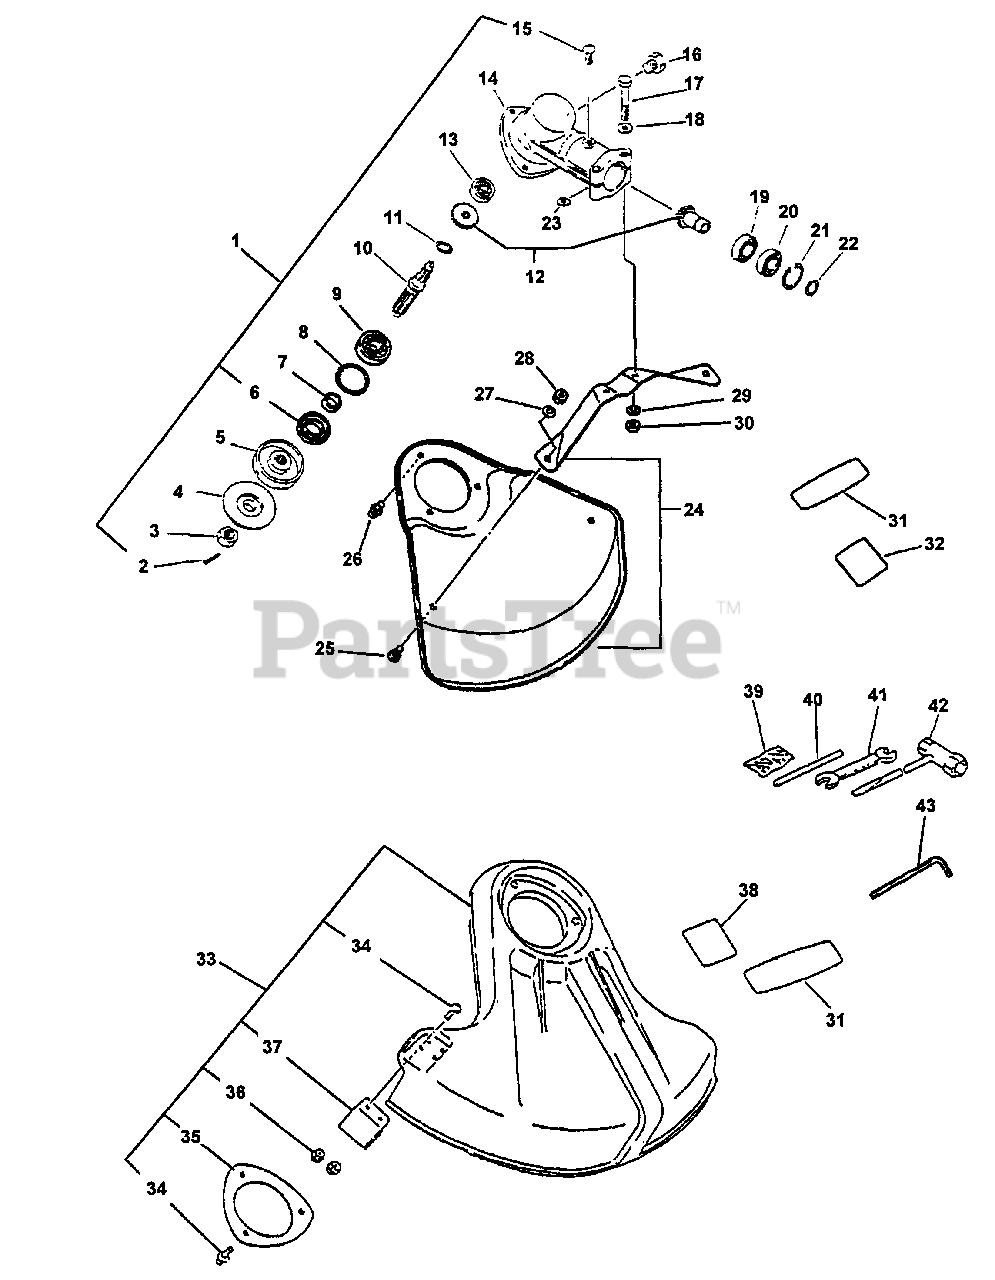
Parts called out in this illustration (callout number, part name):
1	CASE, GEAR - UPPER
2	PIN, SPLIT - 2X22
3	NUT - 10 -- LEFT HAND
4	ADAPTOR, BLADE - LOWER
5	ADAPTOR, BLADE - UPPER
6	SEAL, OIL
8	RING, RETAINING - 32
9	BEARING, BALL - 6201
10	GEAR - SHAFT
11	RING, RETAINING - 10
12	GEAR SET - BEVEL
13	BEARING, BALL - 609
14	CASE, GEAR
15	SCREW - 5X10
16	BOLT - 8X8
17	BOLT - 5X35
18	WASHER - 5
19	BEARING, BALL - 6900
20	BEARING, BALL - 6900Z
21	RING, RETAINING - 22
22	RING, RETAINING - 12
24	DEBRIS SHIELD KIT - METAL
25	SCREW - 5X8
26	SCREW - 5X10
27	LOCKWASHER - 5
29	LOCKWASHER - 5
31	LABEL - ECHO
32	LABEL - DANGER
33	DEBRIS SHIELD KIT
34	SCREW - 5X16
35	PLATE, SHIELD
37	KNIFE, TRIMMER LINE
38	LABEL - CAUTION
39	PIN, SPLIT - 2X22
40	LOCKING TOOL
41	SPANNER - 8X10mm
42	T-WRENCH - 17X19mm
43	HEX KEY - 3mm
